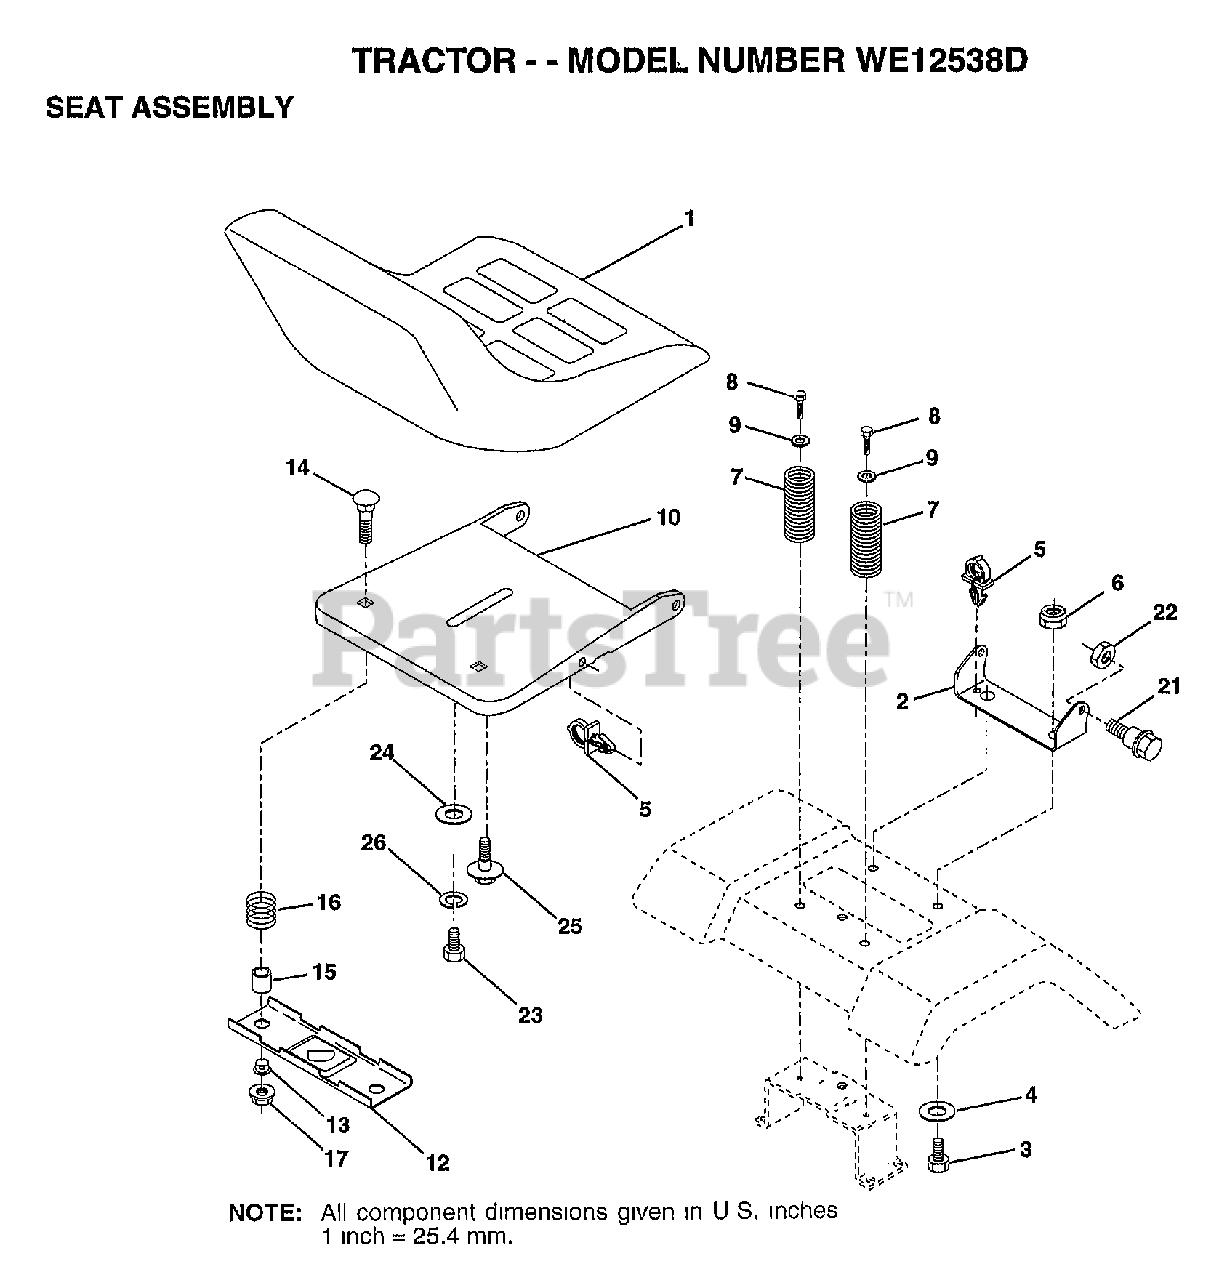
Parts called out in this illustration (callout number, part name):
2	BRACKET PVT SEAT
3	BOLT
4	WASHER PM
5	CLIP.PUSH-IN.HING
6	NUT
7	SPRING COMPRESSIO
8	SCREW GTV
9	WASHER
10	PAN-SEAT
12	BRKT SWITCH
13	BUSHING
15	SPLIT SPACER
16	SPRING
21	"BOLT,SHOULDER"
22	NUT
23	BOLT
24	WASHER
25	"BOLT,SHOULDER"
26	LOCKWASHER
